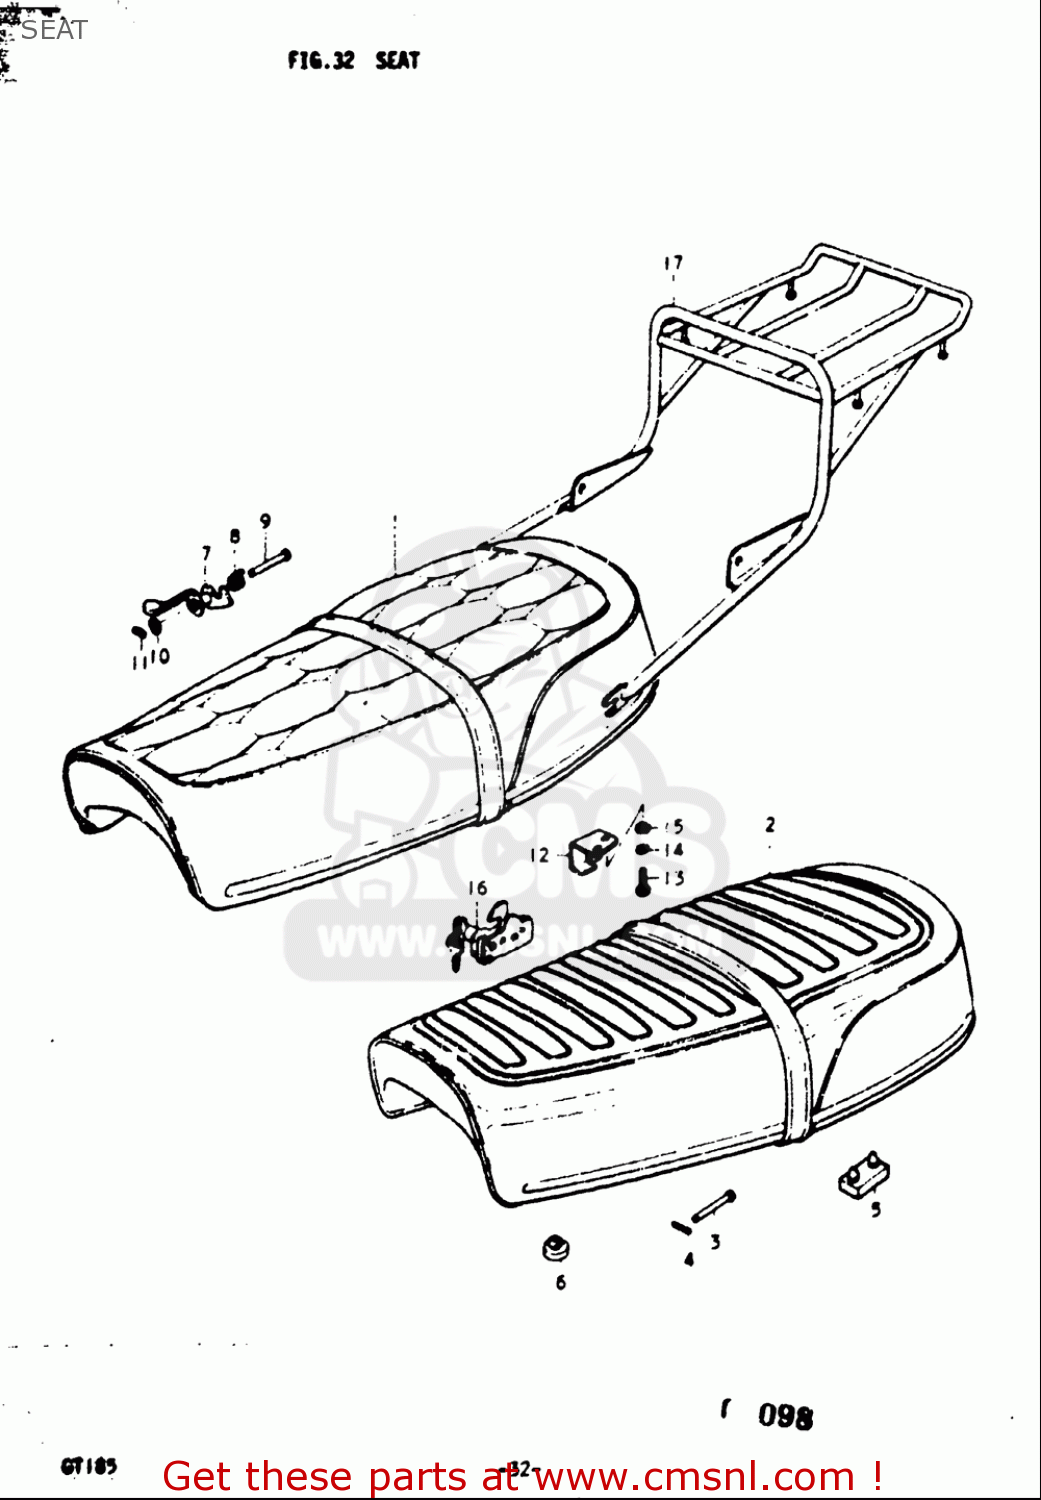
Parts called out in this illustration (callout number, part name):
3	PIN
4	PIN
5	CUSHION
6	CUSHION(11.5X22X20)
8	SPRING
9	PIN
10	WASHER
12	PLATE,SEAT CLAMP GUIDE
13	BOLT
14	WASHER,LOCK
15	WASHER
